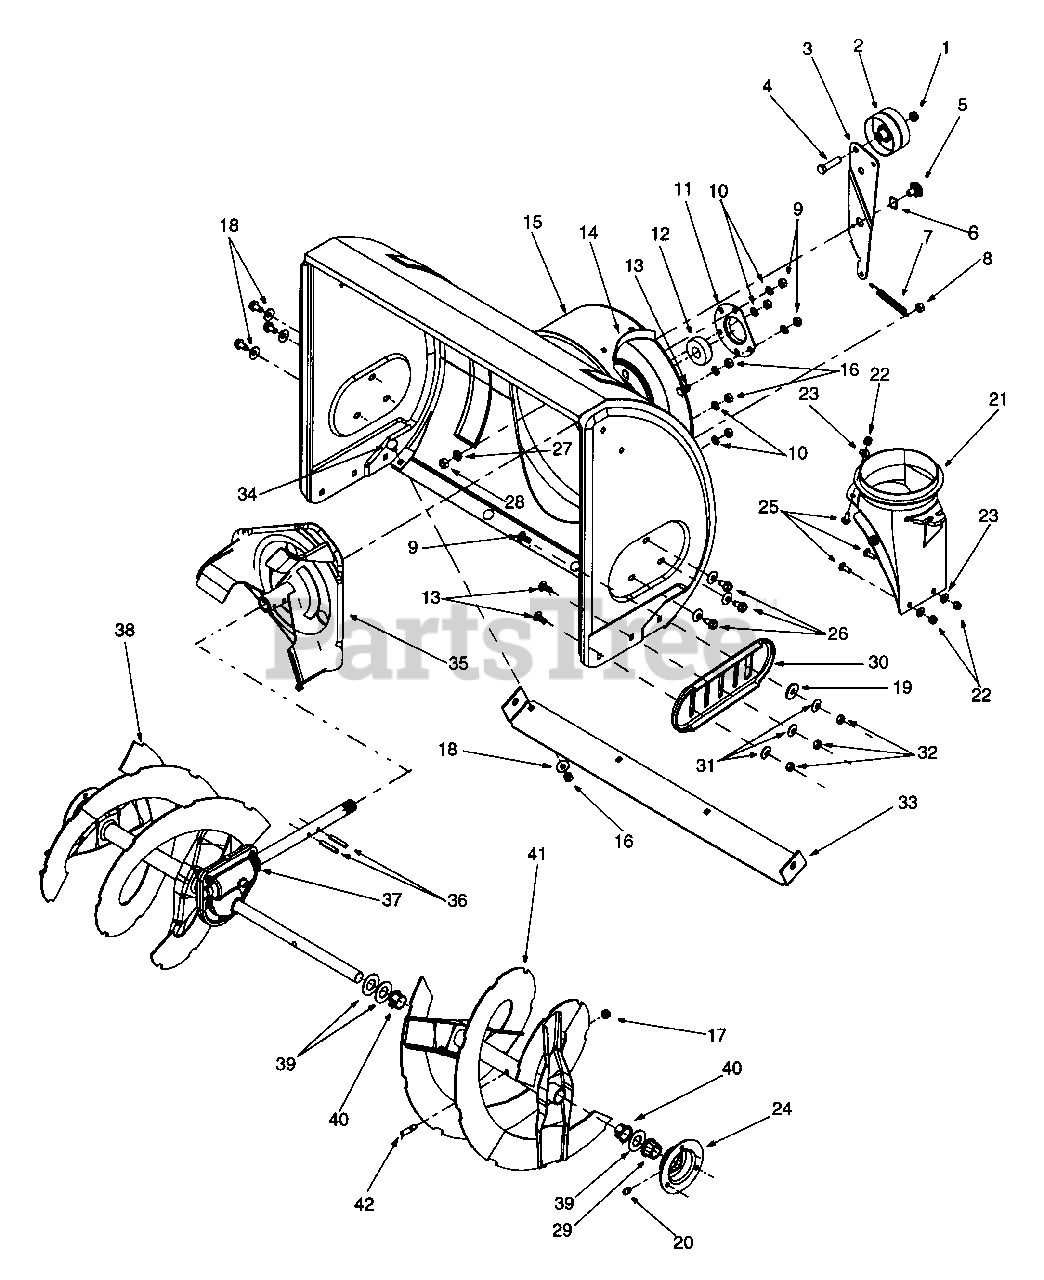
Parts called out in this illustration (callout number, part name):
1	Lock Jam Nut 3/8-24
2	Flat Idler
3	Auger Idler Arm
4	Hex Cap Screw 3/8-24 x 1.50
5	Shoulder Screw
6	Wave Washer
7	Extension Spring
8	Hex Nut 5/16-18
9	Carriage Bolt, 5/16-18 x 1.00
10	Lock Washer 5/16
11	Housing
12	Ball Bearing
13	Carriage Bolt, 5/16-18 x.75
17	Lock Nut 5/16-18
18	Belleville Washer
19	Flat Wshr, .344 ID x 1.125 OD
20	Grease Fitting, 3/16" Drive
21	Chute Adapter
22	Hex Lock Nut 1/4-20
23	Flat Washer
24	Bearing Housing w/Fitting
25	Carriage Screw 1/4-20 x .75
26	Hex Screw 5/16-18
27	Lock Washer 3/8
28	Hex Nut 3/8-16
29	Hex Flange Bearing
30	Skid Shoe
31	Bell Washer
32	Hex Nut 5/16-18
33	Shave Plate
34	Carriage Bolt 5/16-18 x .62
35	Impeller Assembly
36	Pin
37	30" Gear Assy
37	26" Gear Assy
38	30" Spiral RH
38	26" Spiral RH
39	Flat Washer
40	Flange Bushing
41	30" Spiral LH
41	26" Spiral LH
42	Shear Bolt 5/16-18 x 1.5
